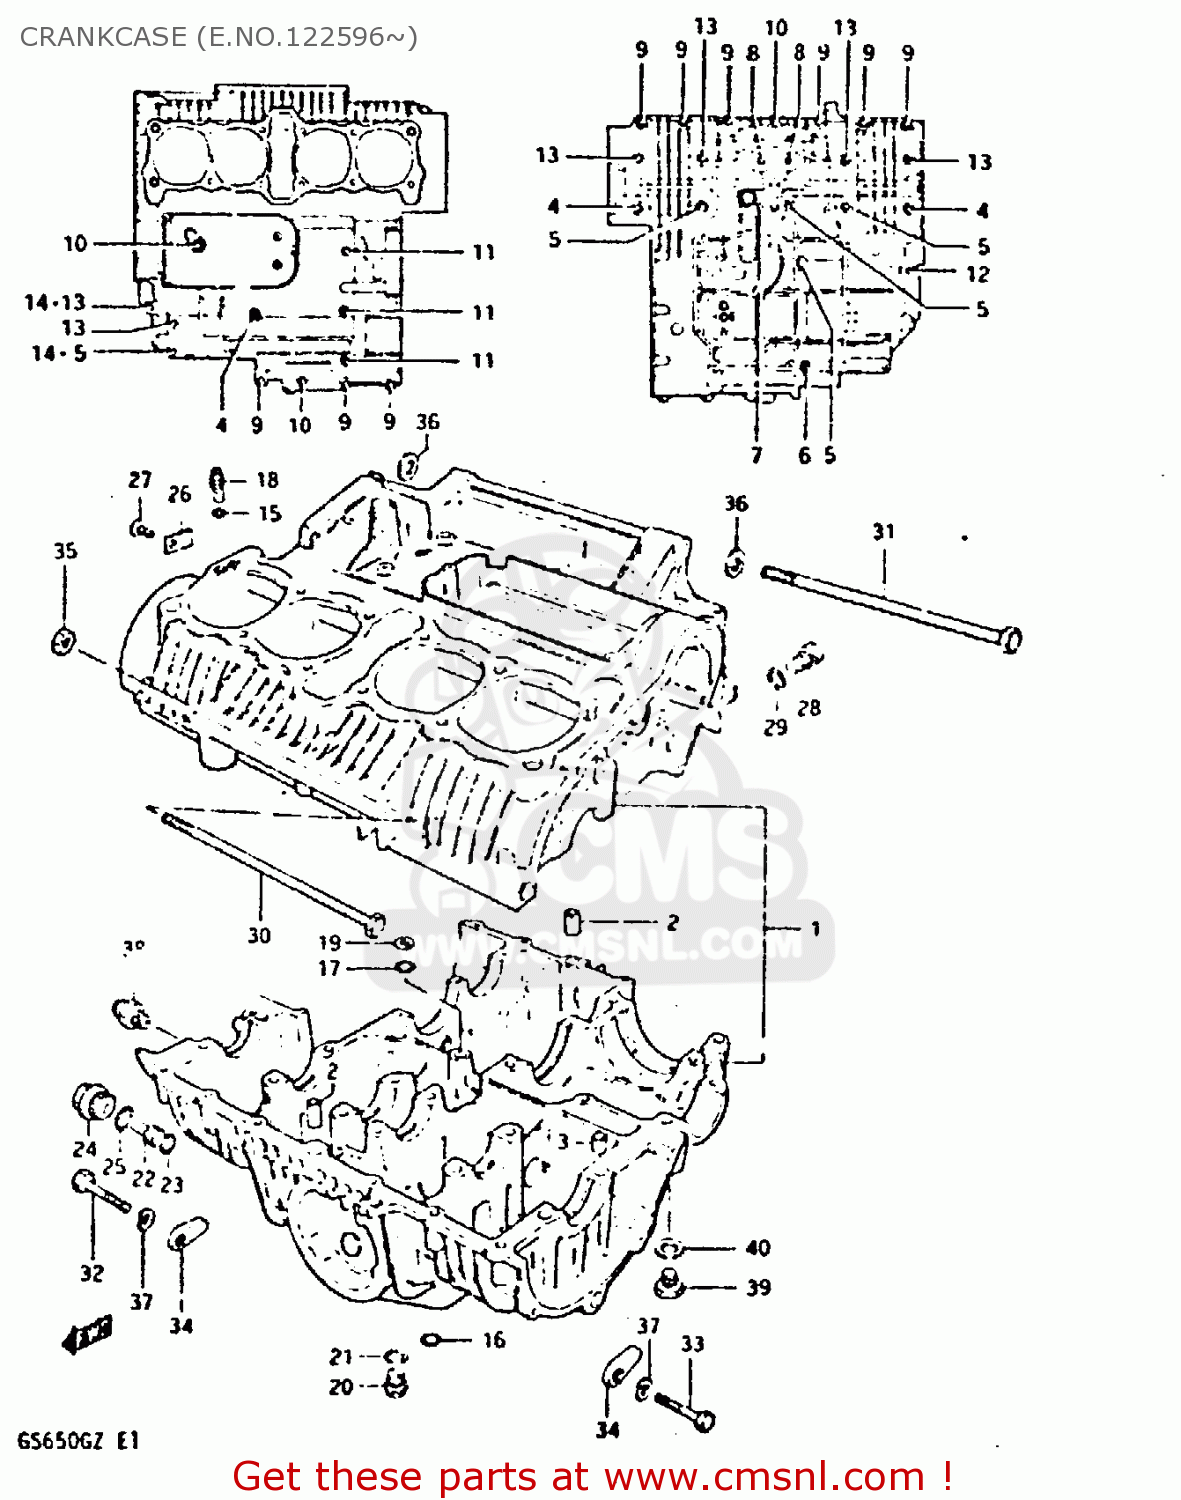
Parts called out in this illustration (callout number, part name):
1	CRANKCASE SET
2	PIN (11X20)(SUS)
3	PIN(10.4X13X22)
4	BOLT
5	BOLT
6	BOLT (8*135)
7	BOLT(8X140)
8	BOLT
9	BOLT
10	BOLT
11	BOLT (6X90)
12	BOLT (8X70)
13	BOLT (8X95)
14	NUT
15	O-RING,OIL GALLERY JET
16	O-RING
17	O RING(D:3.2,ID:12.9)
18	JET(12)
19	WASHER
20	PLUG
21	GASKET(16X22X2) (NAS)
22	PIN,OIL GALLERY
23	SEAL (D:1.9 ID:9.8)
24	PLUG
25	O RING(D:2.4,ID:17.8)
26	PLATE,OIL GALLERY PLUG
27	SCREW
28	PLUG
29	GASKET(12.1X16.2X3.7) (NAS)
30	BOLT
31	BOLT 10X250
32	BOLT 10X55
33	BOLT 10X40
34	NUT
35	NUT 10MM
36	WASHER
37	LOCK WASHER
38	SWITCH ASSEMBLY
39	PLUG
40	GASKET(14X19.2X2) (NAS)
